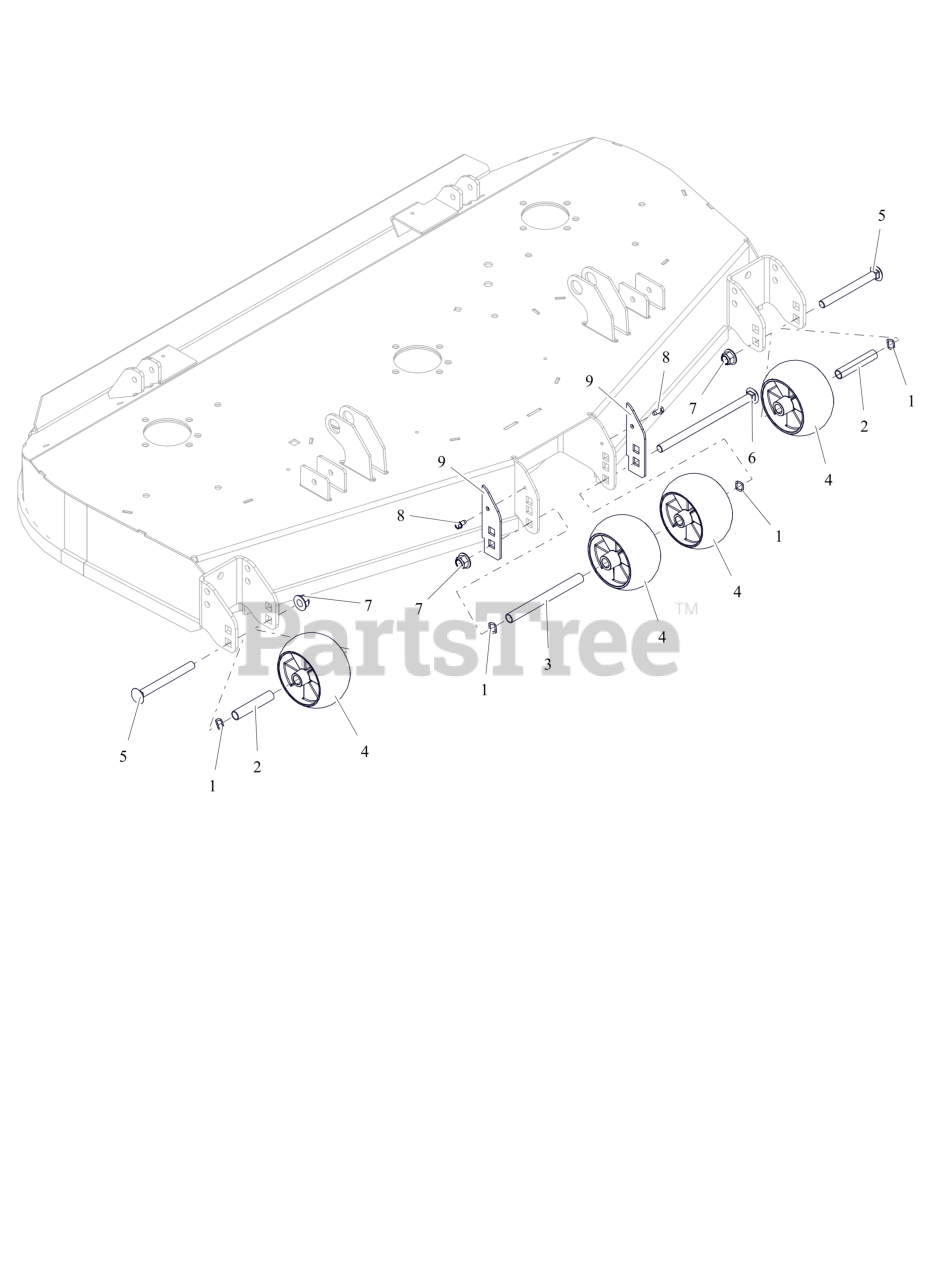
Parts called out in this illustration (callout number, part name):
1	WAVE WASHER .531X.781X.125FH
2	SPACER, .510X.625X3.35
3	SPACER, .510X.625X6.50
4	ANTI-SCALP WHEEL - 5X3 CTR
5	BLT, RHSN .50-13X5.00 G5 ZCC
6	BLT, RHSN .50-13X8.50 G5 ZCC
7	NUT,NYL-FLG .50-13 GF ZCC
8	SCR-TAP .25-20X.50 HWH ZCC
9	PLATE, ANTI SCALP WHEEL PLATE CE (ORANGE)
